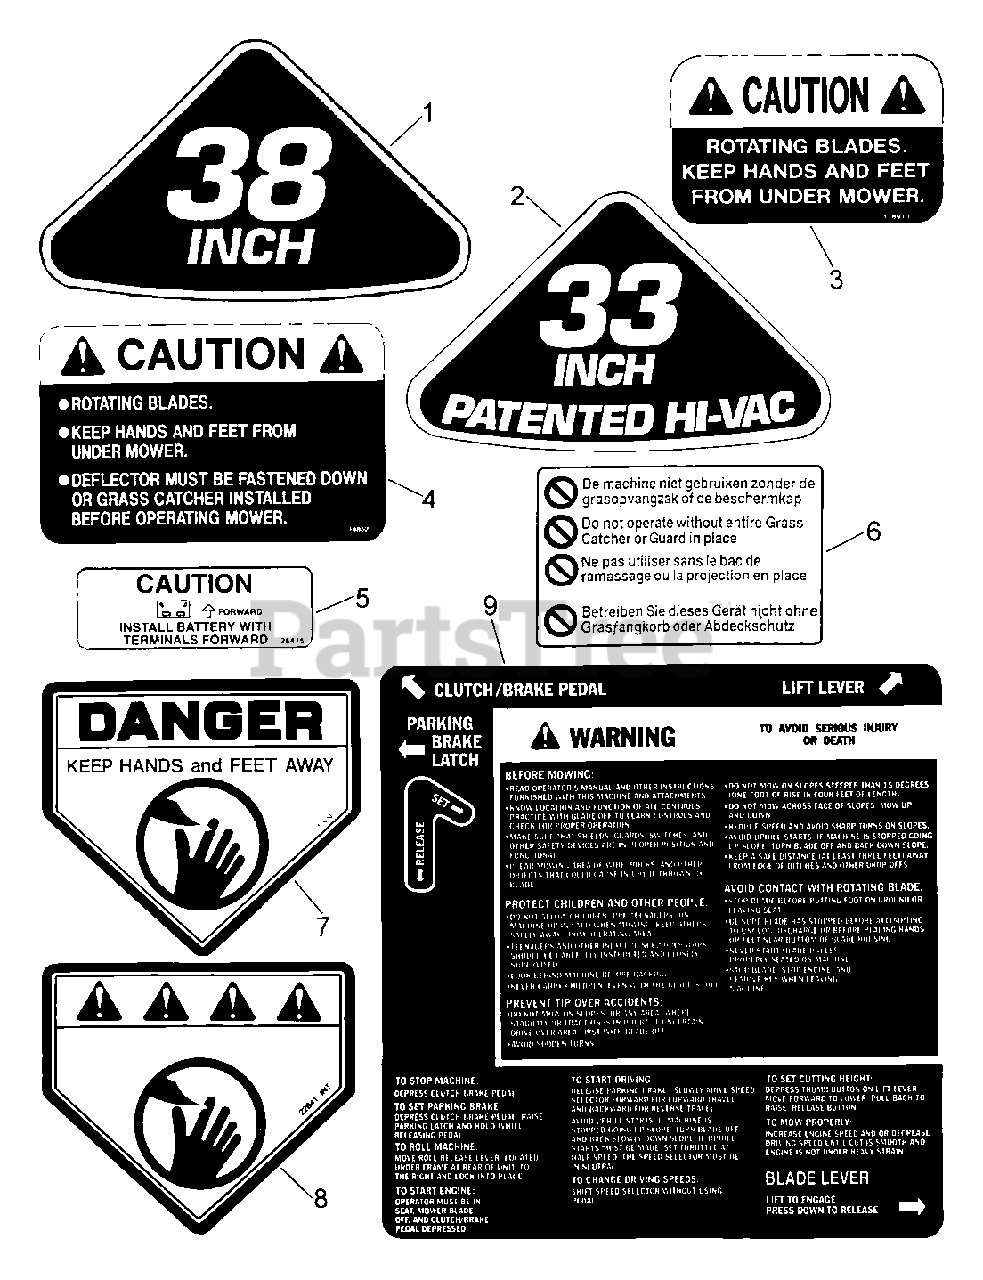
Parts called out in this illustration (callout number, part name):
1	DECAL, 38 Inch
2	DECAL, 33 Inch Hi-Vac
3	DECAL, Caution, Rotating Blades
4	DECAL, Caution, Rotating Blades
5	DECAL, Caution, Battery Location
6	DECAL, Deck/Chute International Warning
7	DECAL, Danger, Cut-Finger
7	DECAL, Danger, Cut-Finger (Heavy Adhesive Version)
8	DECAL, Cut-Finger (European Only)
9	DECAL, Instructions, Frame, Top
9	DECAL (German Version of Above)
9	DECAL (French Version of Above)
9	DECAL (Spanish Version of Above)
9	DECAL (Italian Version of Above)
